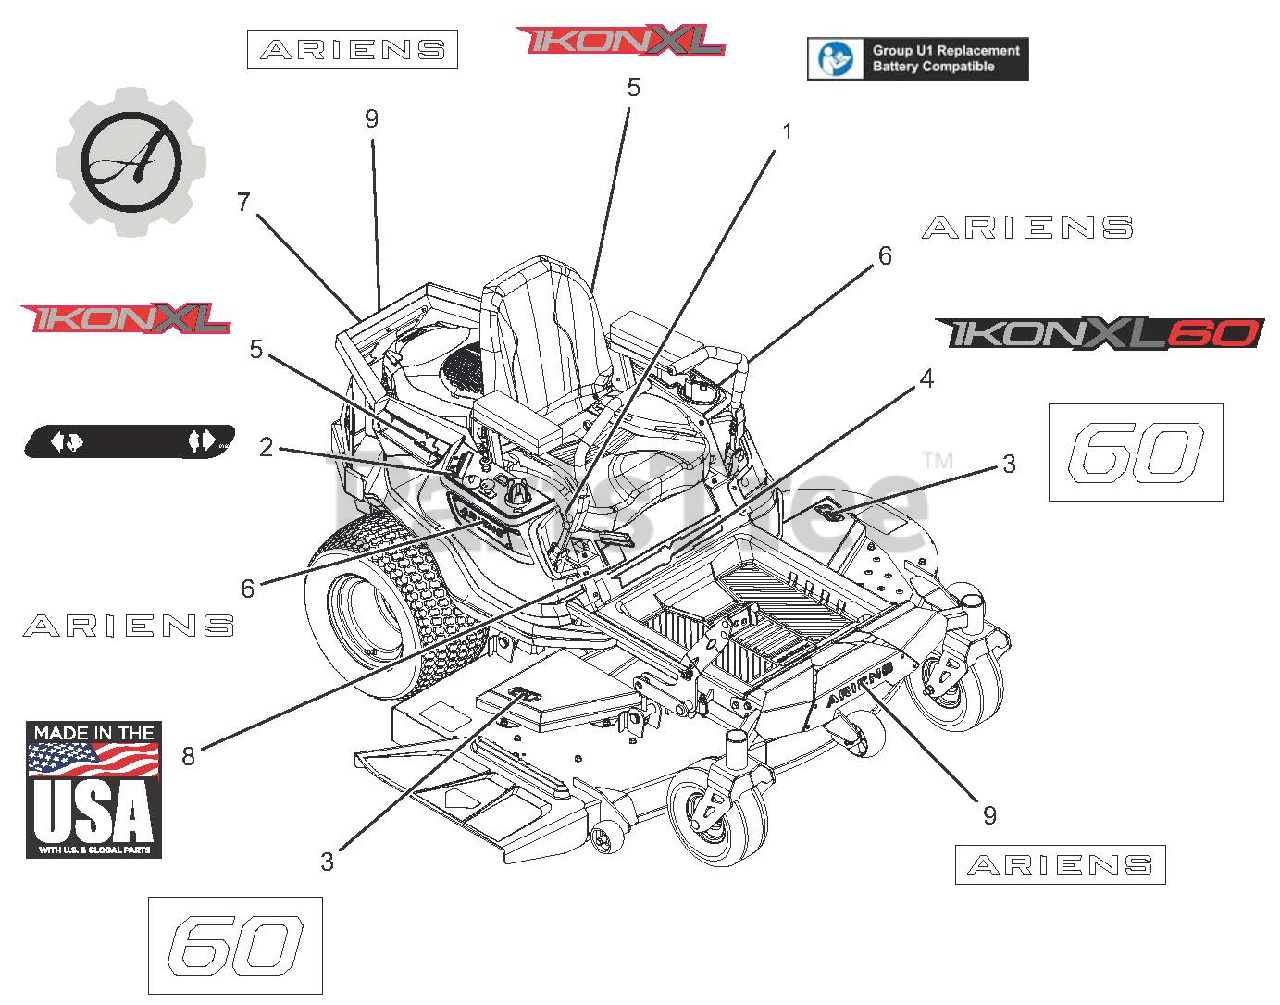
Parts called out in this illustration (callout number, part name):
1	DECAL, U1 BATTERY REPLACEMENT
2	DECAL, DASH DECAL
3	DECAL, 60"
4	DECAL, IKON-XL 60"
5	DECAL, IKON-XL
6	DECAL, ARIENS (6.50")
7	DECAL, ARIENS-GEAR BADGE
8	DECAL, MADE IN USA
9	DECAL - ARIENS 9.625"
